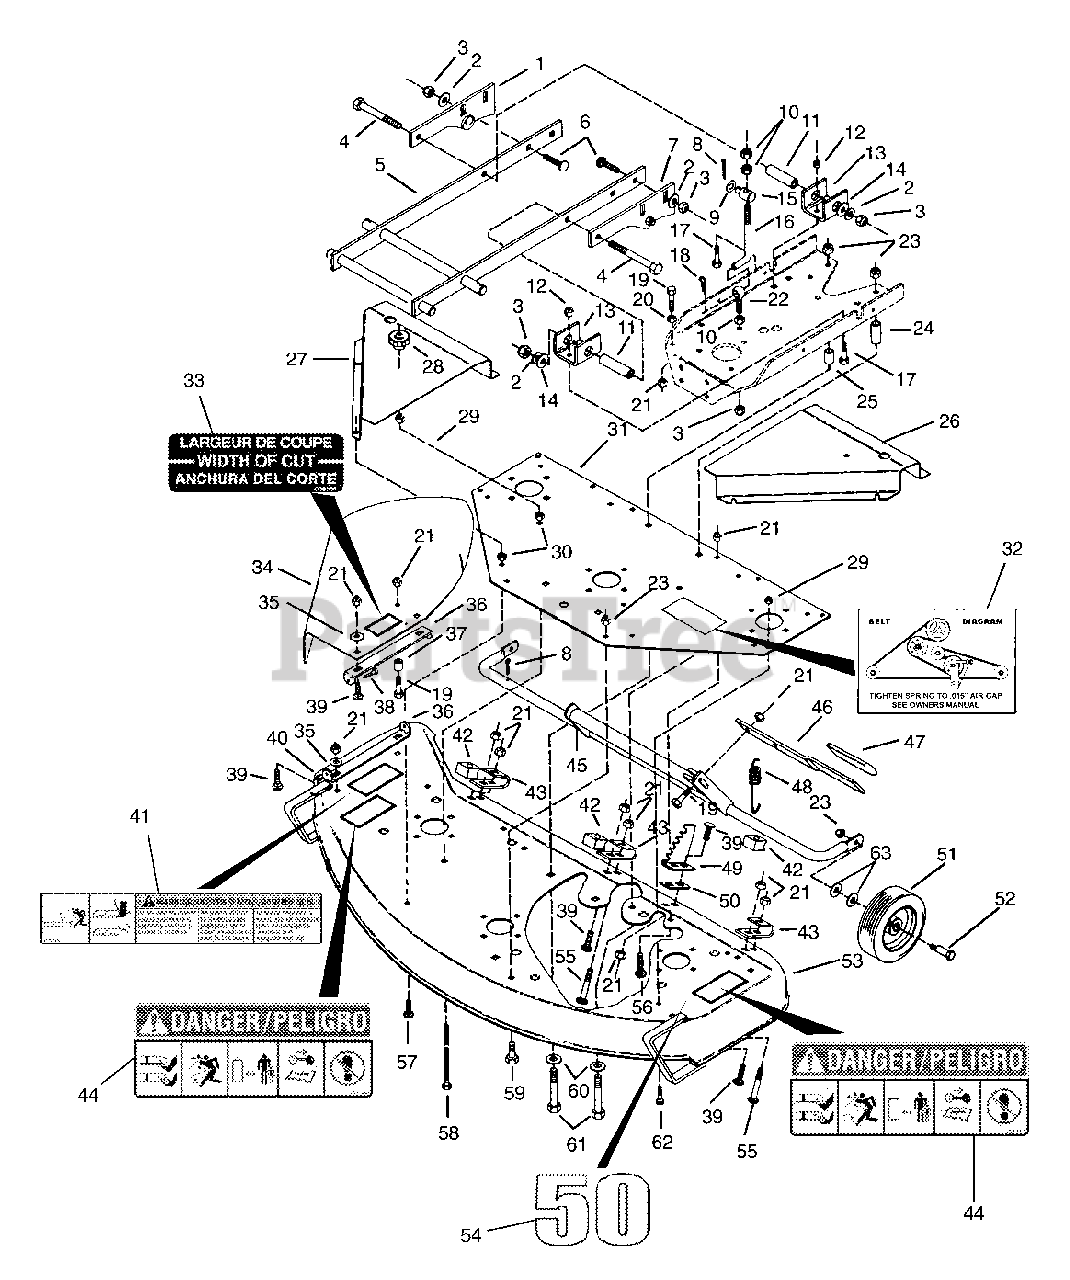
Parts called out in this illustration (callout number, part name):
1	Weldment, Deck Leveling Right Hand
2	Washer-Flat-Steel .531 x 1.25 x .100
3	Nut-Locking-Center .50-13
4	Bolt-Hex .50-13 x 3.25 Grade 5
5	Weldment, Pivot Arm
6	Bolt-Round Head Square Neck .50-13 x 1.25 Grade 5
7	Weldment, Deck Leveling Left Hand
8	Pin-Cotter .12 x 1.25
9	Washer-Flat-Steel .531 x 1.000 x .063
10	Nut-Jam .50-13
11	Spacer .510 x .750 x 2.02 Steel
12	Nut-Locking-Center .31-18
13	Support, Mower Pivot
14	Washer-Flat-Steel .813 x 1.370 x .100
15	Pivot, Mower Lift
16	Rod, Lift
17	Bolt-Hex .31-18X.875 Grade 5
18	Pin-Cotter .12 x 2.0
19	Bolt-Hex .38-16 x 1.50 Grade 5
20	Nut-Jam .375-16
21	Nut-Locking-Nylon .38-16
22	Bolt, Eye
23	Nut-Locking-Nylon .50-13
24	Spacer .510 x .840 x 2.437 Steel
25	Rod, PTO Control
26	Cover, Pulley Left Hand
27	Cover, Pulley Right Hand
28	Knob
29	Nut-Locking-Nylon .312-18
30	Nut-Jam .312-18
31	Plate,Support 50
32	Decal, Belt Installation
33	Width of Cut Decal
34	Shield, Safety External Weldment 50" Mower
35	Washer-Flat-Steel .406 x .812 x .065
36	Bracket, Chute
37	Bushing-Sleeve .407 x .625 x .750
38	Bolt-Hex .25-20 x .875
39	Bolt-Round Head Square Neck .38-16 x 1.00
40	Nut-Locking-Nylon .25-20
41	Decal, Mower Pan Danger
42	Stop, Nylon
43	Bracket, Axle Support
44	Decal, Warning
45	Weldment, Axle Pivot
46	Lever, Height of Cut
47	Grip, Handle
48	Spring-Tension .095 x .85 x 4.38
49	Bracket, Height Adjustment
50	Shim, Mower Height Adjuster Bracket
51	Tire/Wheel Assembly 6 x 2
52	Bolt, Eccentric
53	Weldment, 50" Mower Deck
54	Decal, 50
55	Bolt-Round Head Square Neck .38-16 x 2.00 Grade 5
56	Bolt-Round Head Square Neck .50-13 x 1.00 Grade 5
57	Bolt-Round Head Square Neck .31-18 x 1.00 Grade 5
58	Bolt-Round Head Square Neck .31-18 x 3.50 Grade 5
59	Bolt-Hex .50-13 x 1.25 Grade 5
60	Washer-Flat-Steel .531 x 1.06 x .095
61	Bolt-Hex .50-13 x 3.75 Grade 5
62	Bolt-Round Head Square Neck .31-18 x .75
63	Washer-Flat-Steel .511 x 1 .441 x .125
